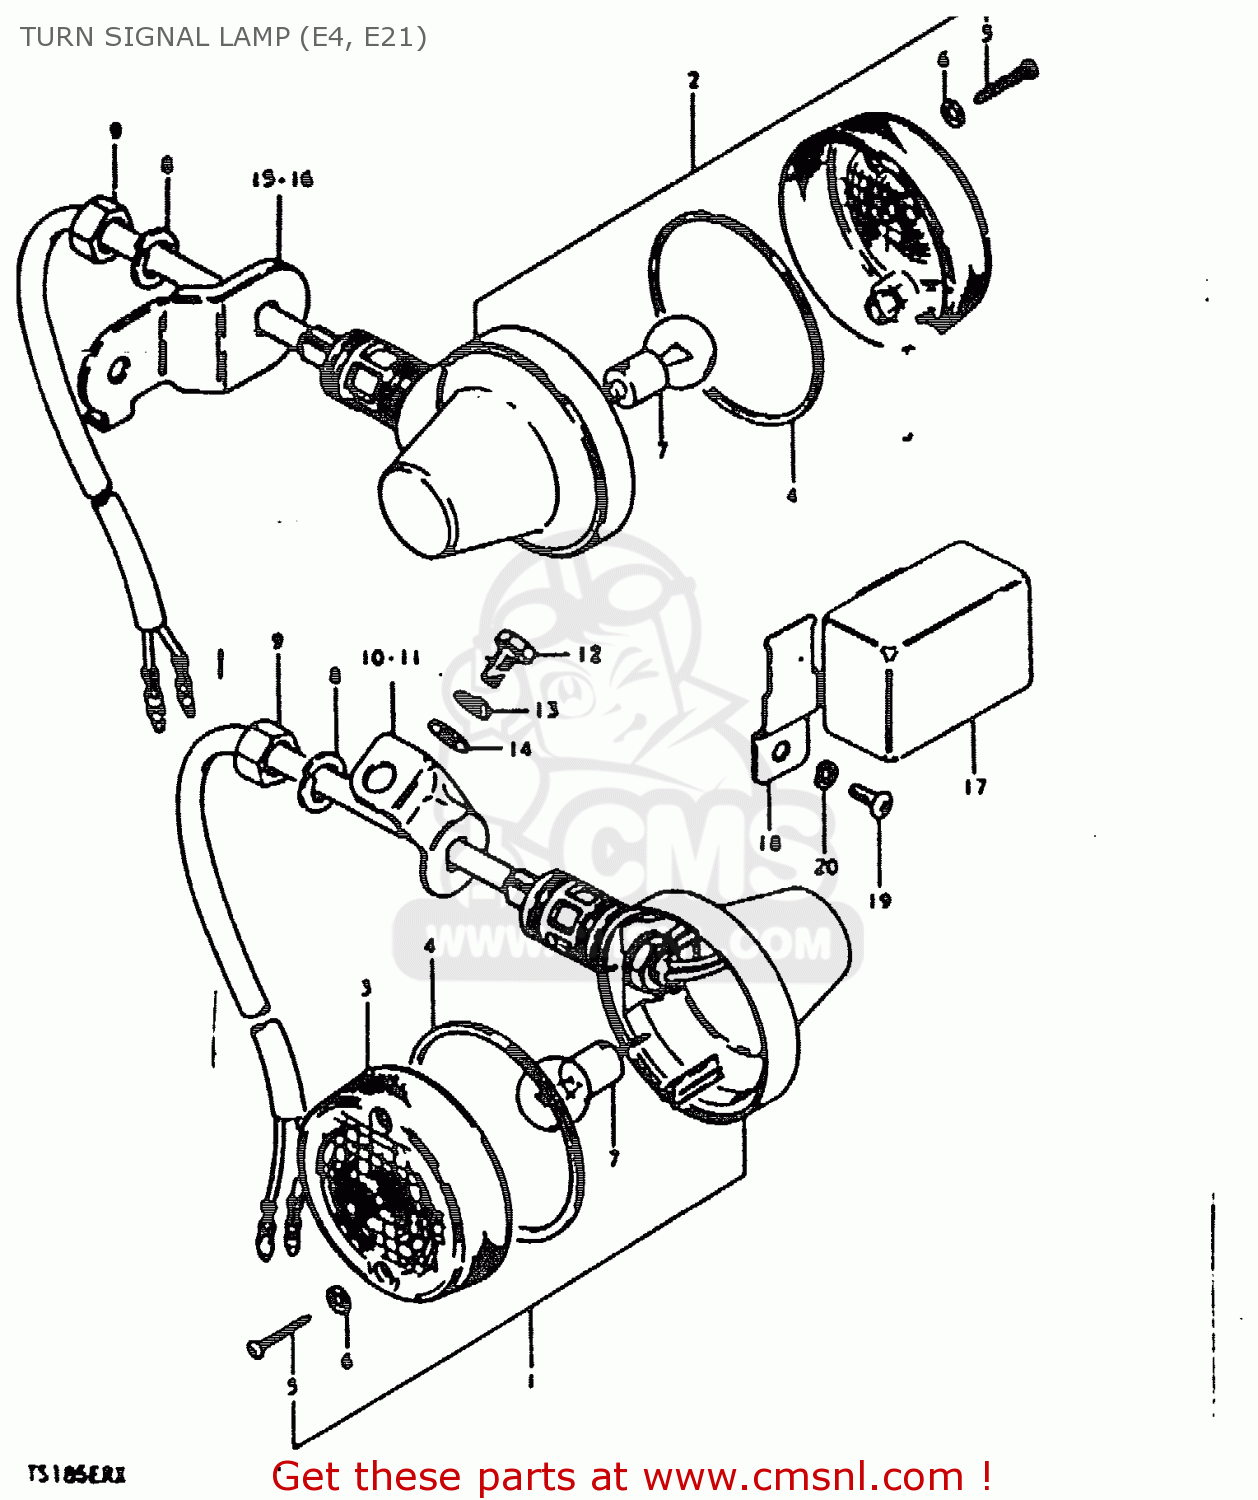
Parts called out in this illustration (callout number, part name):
1	LAMP ASSY,RR TURNSIGNAL
2	LAMP, REAR TURN SIGNAL
3	LENS
4	GASKET (NAS)
5	SCREW TAPP.
6	GASKET (NAS)
7	BULB(6V/10W,STANLEY,A4117)
8	WASHER,LOCK 12
9	NUT
10	BRACKET,TURN SIGNAL LAMP
11	BRACKET,TURN SIGNAL LAMP
12	BOLT
13	LOCK WASHER
14	WASHER
15	BRACKET,REAR TURN SIGNAL
16	BRACKET,REAR TURN SIGNAL
17	RELAY, TURN SIGNAL
18	BRACKET,TURN SIGNAL RELAY
19	SCREW 6X12
20	LOCK WASHER
